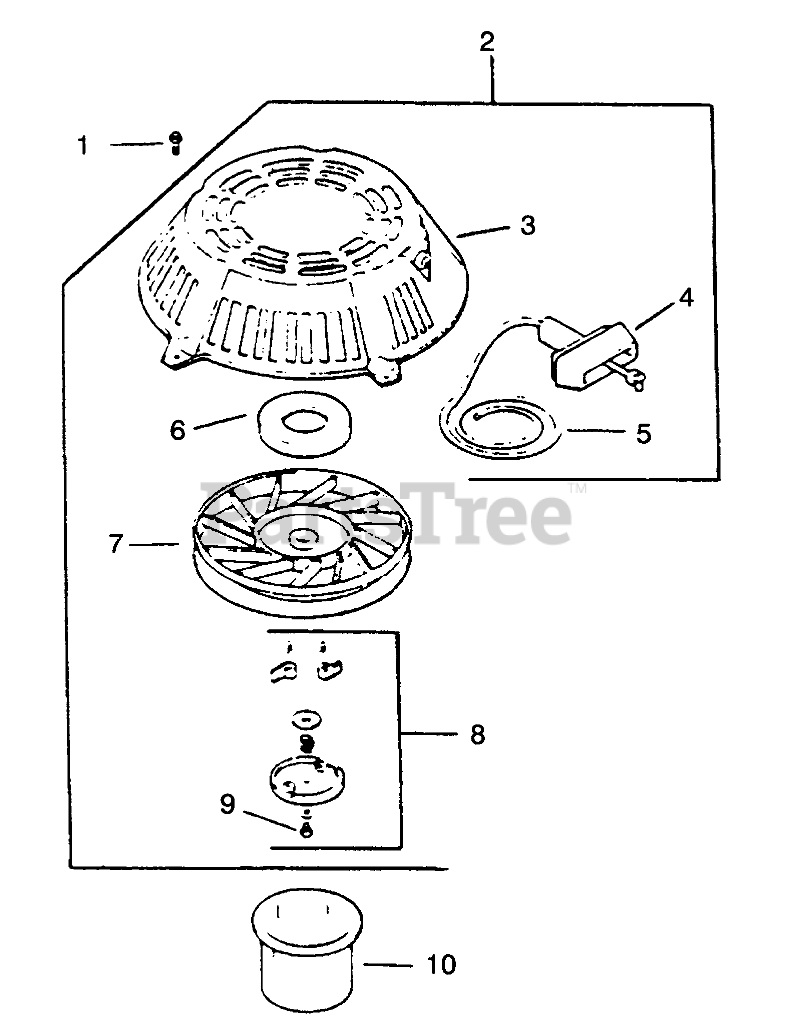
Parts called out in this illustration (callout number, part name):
1	Screw
2	Starter (Incl.Ref.#3-9)
3	Housing-Starter
4	Handle
5	Rope-Starter
6	Spring & Keeper
7	Pulley
8	Kit-Dog Replacement (Incl Ref. #9)
9	Screw-Posidrive
10	Cup-Driver
